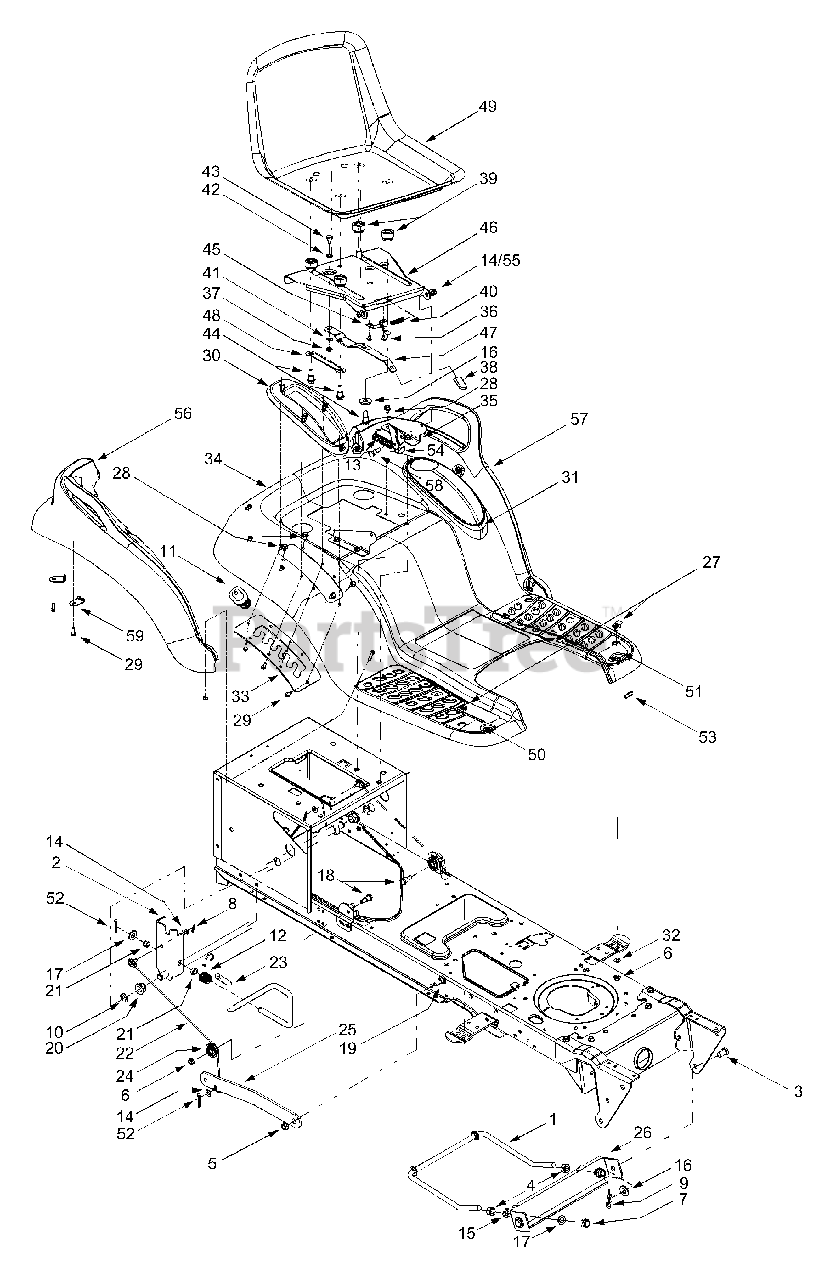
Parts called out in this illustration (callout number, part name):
1	Deck Stabilizer Rod (Model GT-2150)
4	Hex Nut, 1/2-13
5	Flange Lock Nut, 3/8-16
6	Flange Lock Nut, 5/16-18
7	Hex Nut, 1/2-13
8	Internal Cotter Pin
9	Internal Cotter Pin
12	Torsion Spring
13	Extension Spring, .84 x 4.6
14	Flat Washer, 5/16
15	Lock Washer, 1/2
16	Flat Washer, .31 x 1.062 x .134
17	Flat Washer, .51 x 1.12 x .06
18	Hex Cap Screw, 5/16-18 x .62
19	Shoulder Screw, 3/8-16
20	Hex Flange Bearing
21	Snap Flange Bearing
22	Lift Cable, 16.16
24	Roller Pulley
27	Carriage Bolt, 5/16 x .62
28	Self-tapping Screw, 5/16-18 x .625
29	Self-tapping Screw, 1/4-15 x .75
30	Lift Lever Cover
31	Cover w/ Cup Holder
32	Flat Washer, .349 x 1.0 x .063
36	Screw, #10-16 x .375
37	Hex Flange Lock Nut, 1/4-20
38	Seat Adjuster Grip
40	Compression Spring, .41 x 1.5
41	Spring Washer, .265 x .562 x .025
42	Flat Washer, .344 x .62 x .03
43	Shoulder Screw, .340 x .285,1/4-20
44	Shoulder Screw, .50 x .50, 3/8-16
48	Seat Adjustment Selector
49	High Back Seat, Black
54	LH Seat Lift Bracket
56	RH Fender Flare
57	LH Fender Flare
58	Shoulder Screw, .437 x .286
59	Fender Clips
